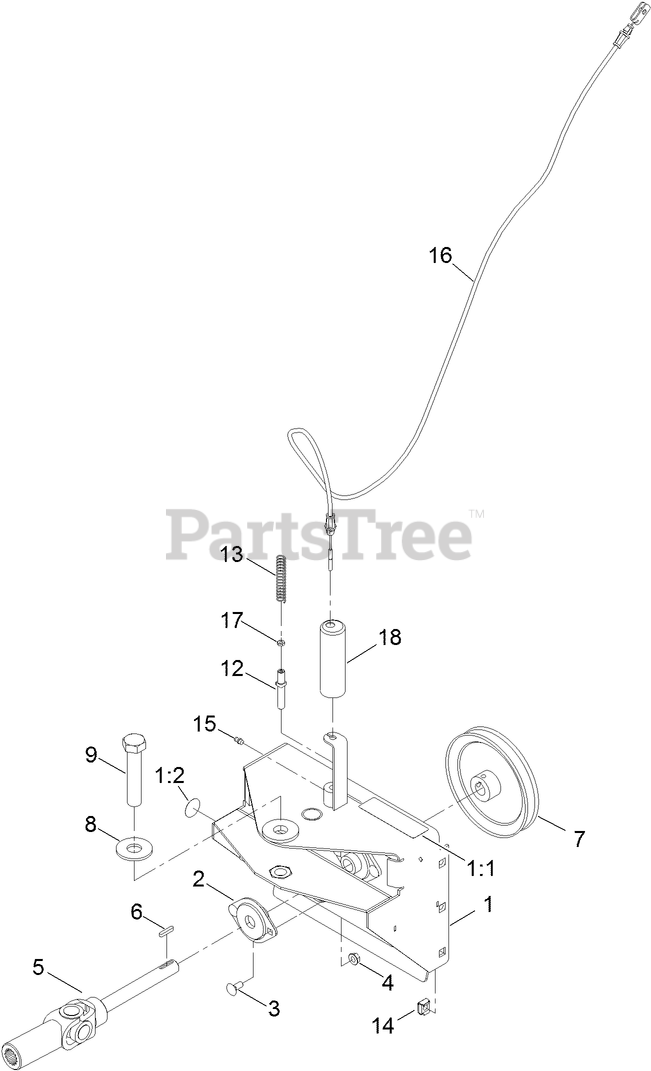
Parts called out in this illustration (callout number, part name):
1	BROOM MOUNTING FRAME ASM
1:1	DECAL-MISSING, COVER
1:2	DECAL-GREASE
2	BEARING-SHAFT
3	BOLT-CARR
4	NUT-HF
5	SHAFT-DRIVE
6	KEY-ROUND END
7	PULLEY-IMPELLER
8	WASHER-FLAT
9	SCREW-HH
12	PIN-SWING
13	SPRING-COMPRESSION
14	NUT-RETAINER
15	FITTING-GREASE
16	CABLE-ANGLE, BROOM
17	NUT-HEX
